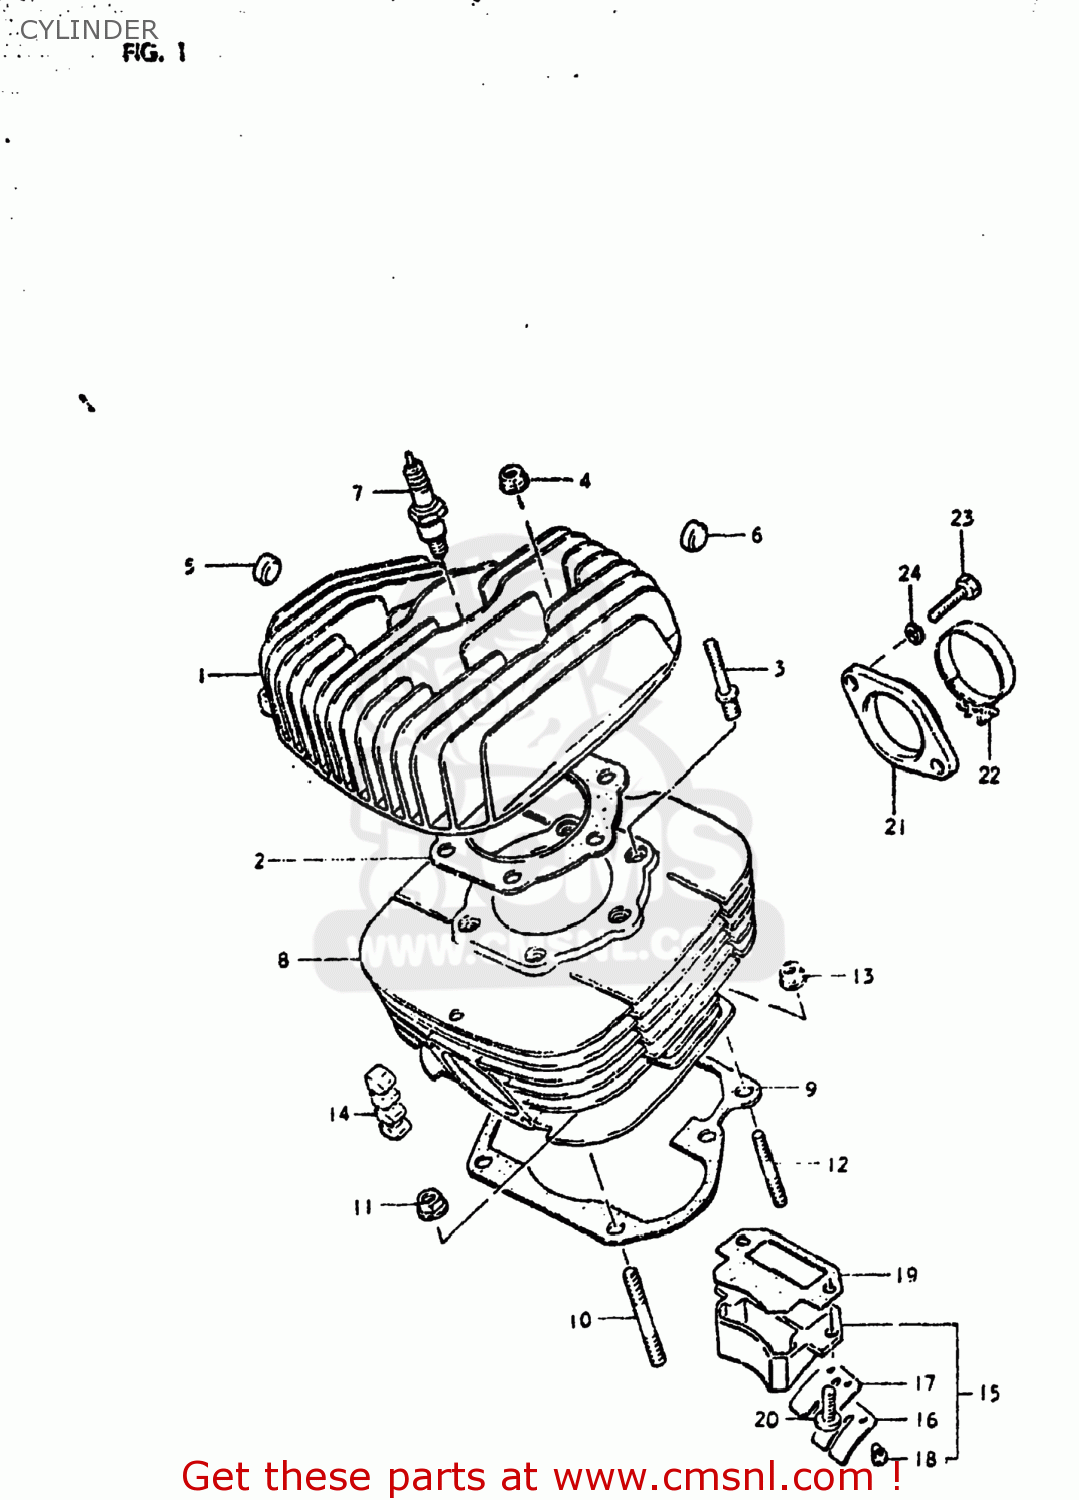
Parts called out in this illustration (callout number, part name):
1	HEAD,CYLINDER
2	GASKET,CYLINDER HEAD (NAS)
3	BOLT,STUD
4	NUT
5	PAD,CYLINDER
6	PAD,CYLINDER HEAD
7	SPARK PLUG W22EP
8	CYLINDER
9	GASKET,CYLINDER (MCA)
10	STUD 10X25
11	NUT
12	STUD 8X25
13	NUT
14	PAD,CYLINDER
15	VALVE ASSY,REED
16	STOPPER,REED VALVE
17	VALVE,REED
18	SCREW,REED VALVE
19	GASKET,REED VALVE (MCA)
20	SCREW
21	PIPE,INTAKE
22	CLAMP
23	BOLT, UPPER
24	LOCK WASHER
